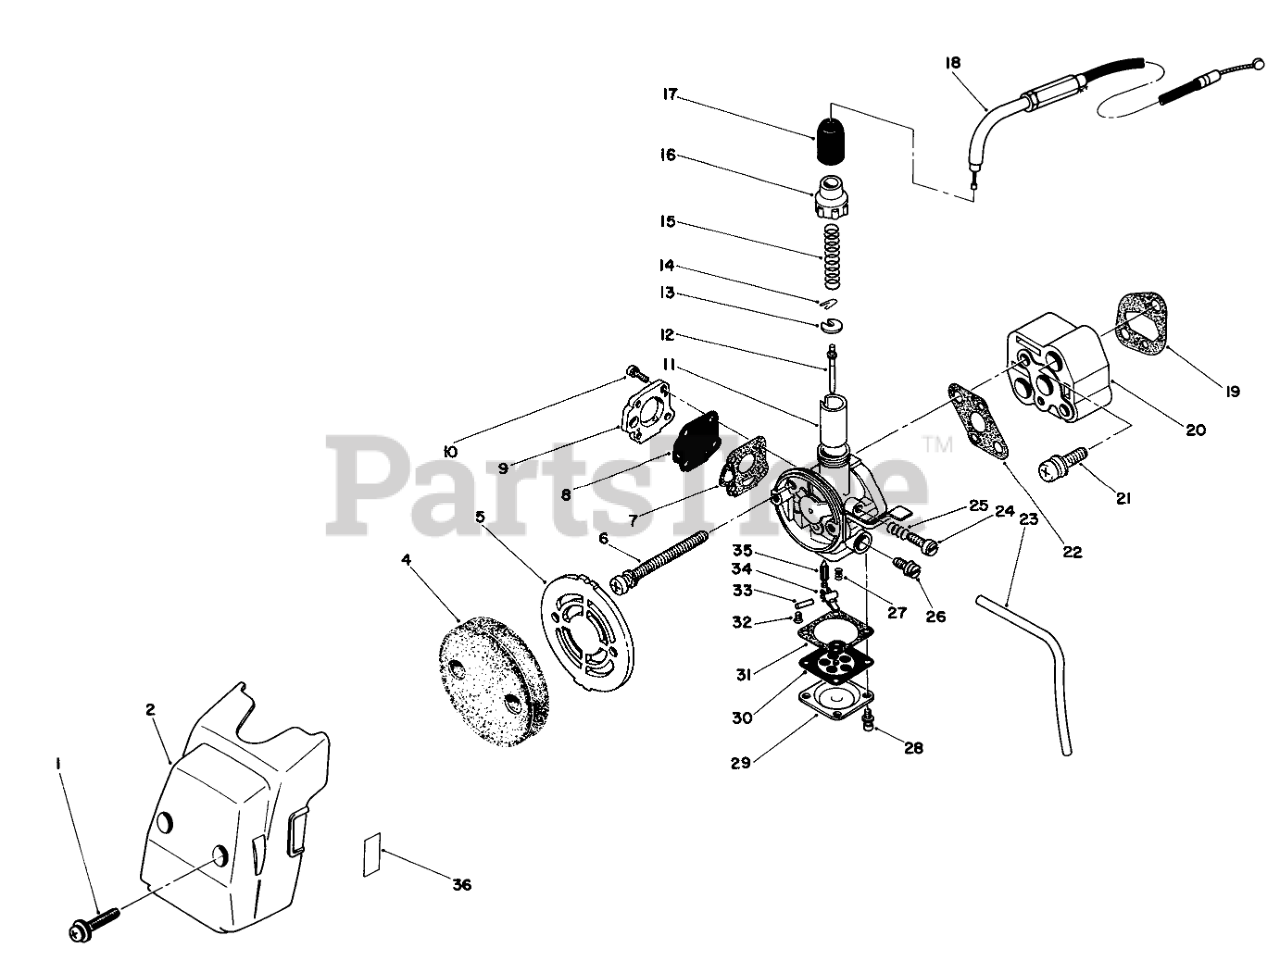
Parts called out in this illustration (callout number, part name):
1	SCREW & WASHER
2	CASE - CLEANER
4	ELEMENT
6	SCREW W/ WASHER
7	PUMP COVER GASKET
8	PUMP DIAPHRAGM
9	Pump Cover Assembly
10	SCREW W/ WASHER
11	THROTTLE VALVE
12	NEEDLE JET
13	SPRING RETAINER
14	NEEDLE CUP
15	SPRING
17	AIR SEAL
18	WIRE, THROTTLE
19	INSULATOR GASKET
20	INSULATOR
21	SCREW & WASHER
22	CARB GASKET
23	FUEL TUBE
24	Screw-Adjusting
25	ADJ. SCREW SPRING
26	MAIN NEEDLE
27	VALVE SPRING
28	SCREW W/ WASHER
29	DIAPHRAGM COVER
30	MAIN DIAPHRAGM
31	DIAPHRAGM GASKET
32	FLOAT SCREW
33	FLOAT PIN
34	FLOAT ARM
35	FLOAT VALVE
36	CHOKE LABEL
